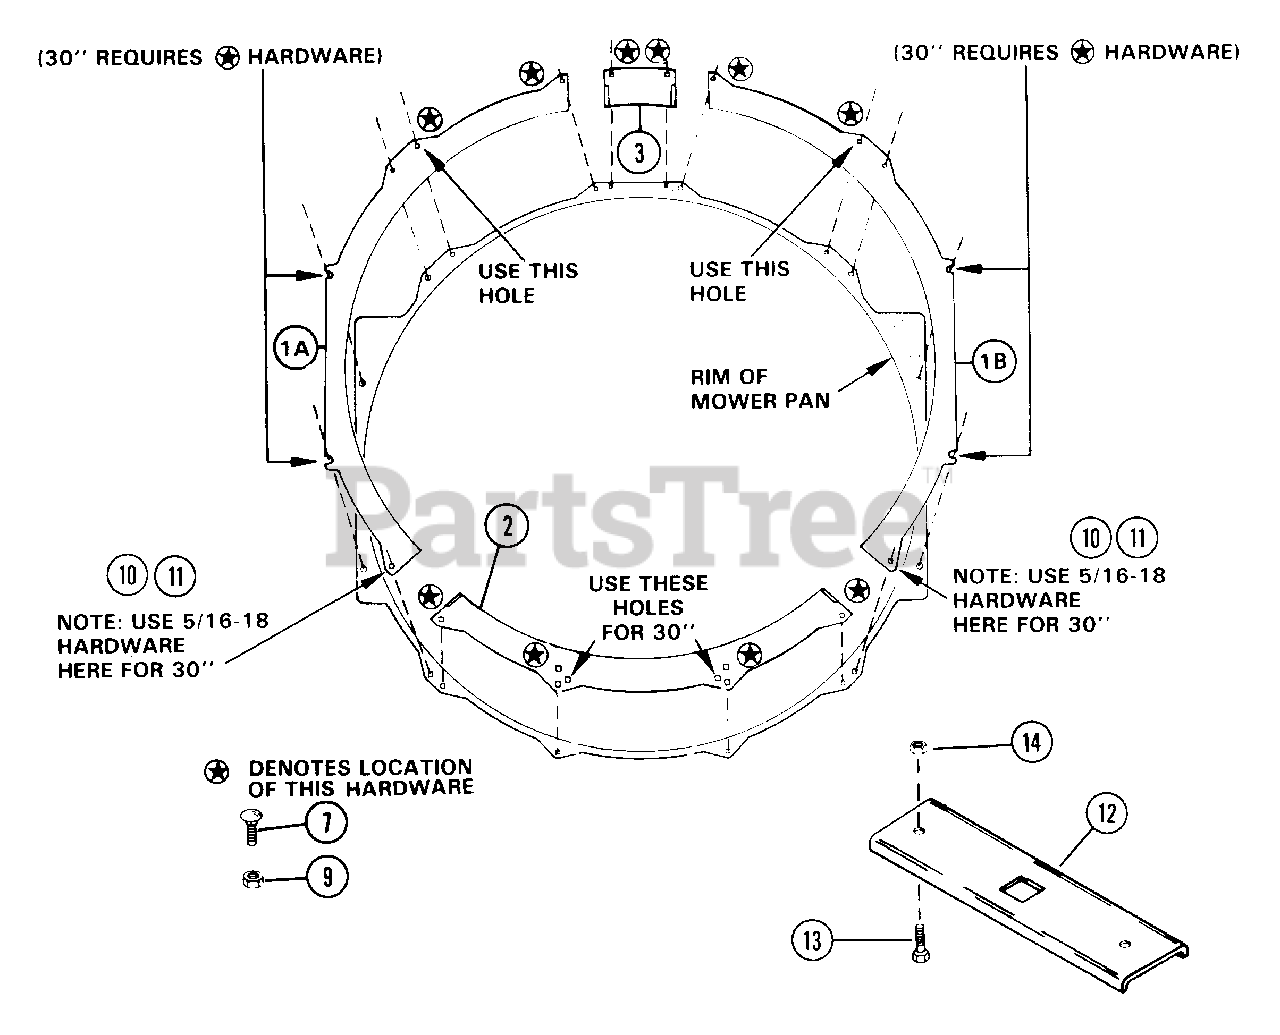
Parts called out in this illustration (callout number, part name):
1	30 IN FLANGE R H
2	BACK FLANGE
3	FRONT CLAMP
7	BLT-RDHDSQNK .25-20X.62 PL
9	NUT-LK-CTR .250-20 PL
10	BLT-RDHDSQNK .312-18X.62SHTPL
11	NUT-LK .312-18 GR A PL
12	BLADE TRAY
13	BLT-HEX .38-16X1.00 PL GR5
14	NUT-LK TOP .375-16 GR C YWZC
